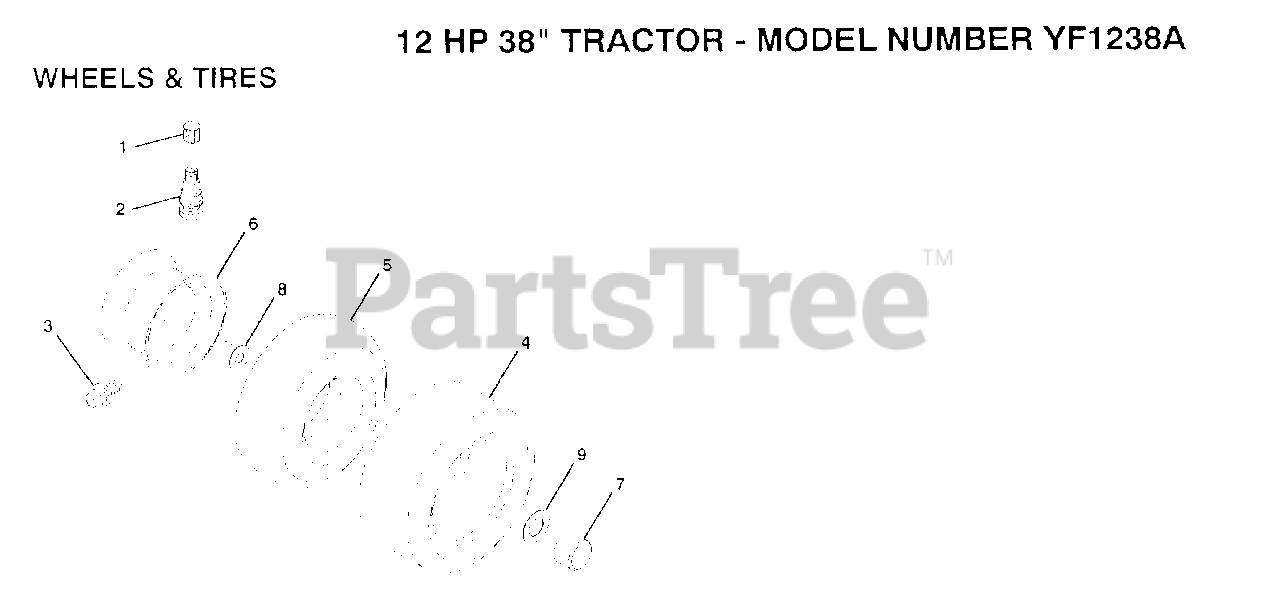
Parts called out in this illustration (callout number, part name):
1	VALVE CAP
2	VALVE STEM LT
3	FITTING LT
5	TUBE.18X9.5-8
5A	TUBE.5.3/4.5/6
7	HUB CAP
8	"FLANGE, BEARING"
9	WASHER
